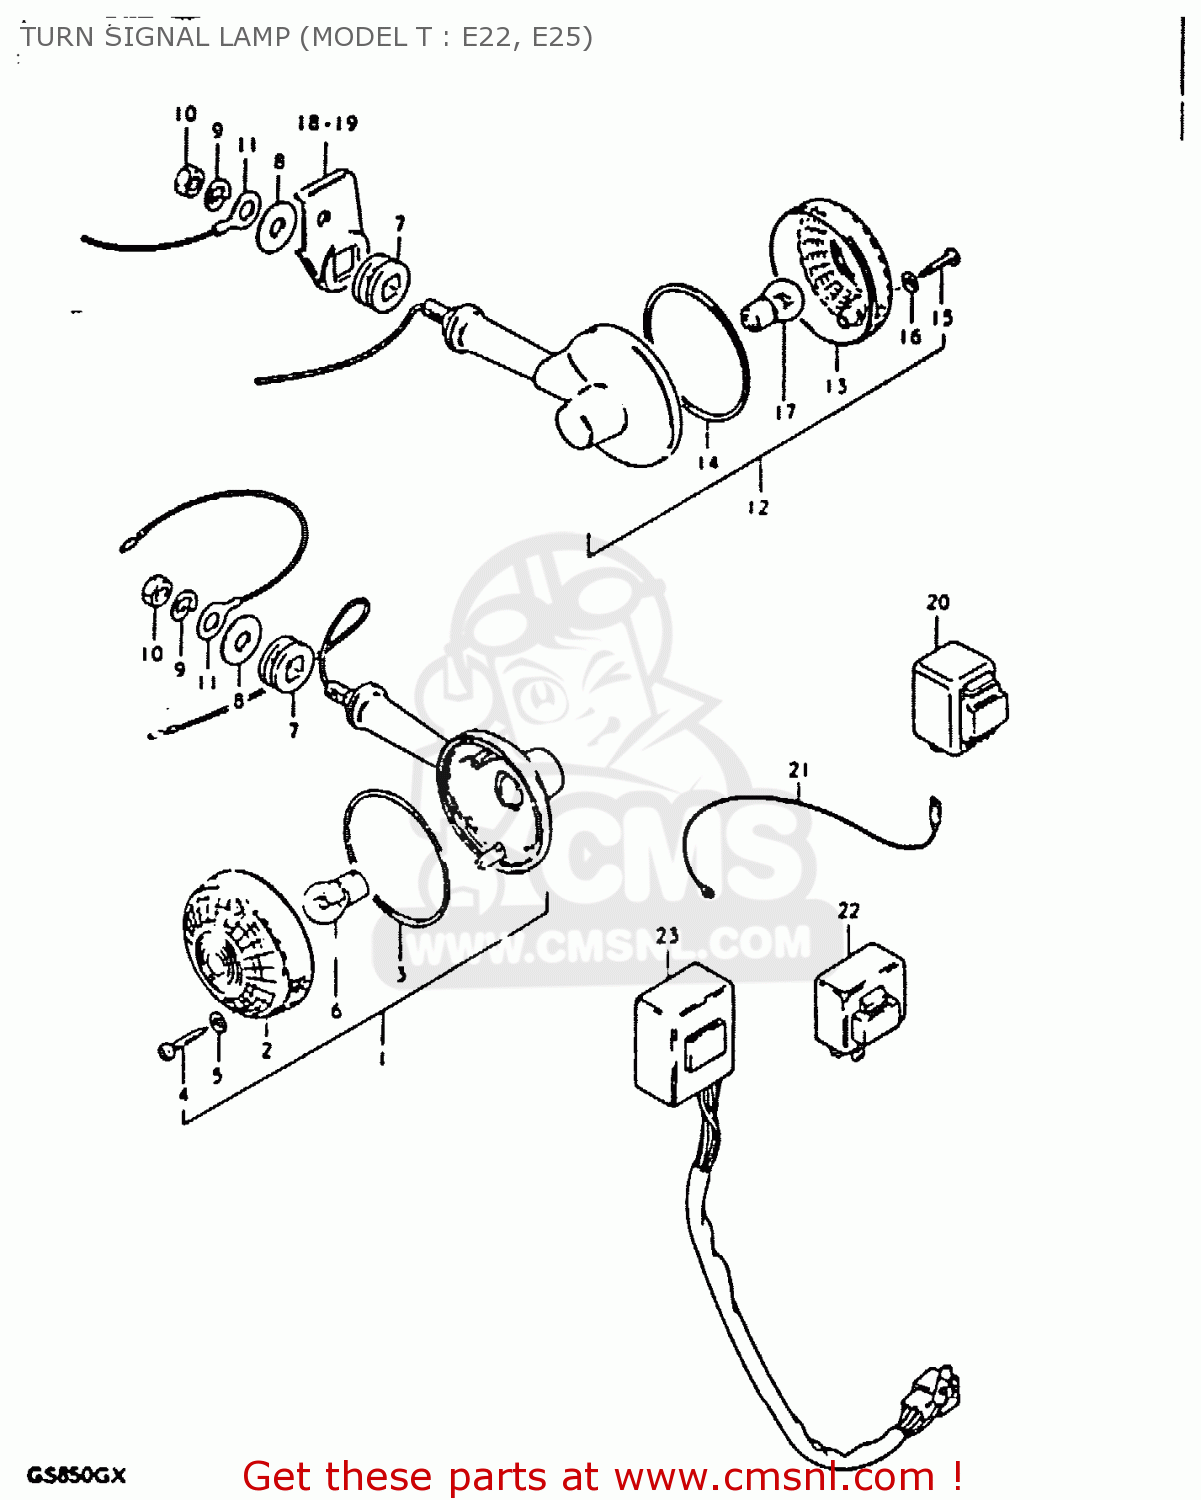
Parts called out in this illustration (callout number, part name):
1	LAMP, REAR TURN SIGNAL
2	LENS
3	GASKET (NAS)
4	SCREW (4X30)
5	GASKET (NAS)
6	BULB(12V21W)
7	CUSHION
8	WASHER (10.5X30X2.3)
9	LOCK WASHER
10	NUT
11	LEAD WIRE,EARTH
12	LAMP, REAR TURN SIGNAL
13	LENS
14	GASKET (NAS)
15	SCREW (4X30)
16	GASKET (NAS)
17	BULB(12V21W)
18	BRACKET,RR TURNSIGNAL LAMP,R
19	BRACKET,RR TURNSIGNAL LAMP,L
20	RELAY, TURN SIGNAL
21	LEAD WIRE, RELAY EARTH
22	RELAY ASSY,TURNSIGNAL
23	UNIT,TURN SIGNAL CONTROL
